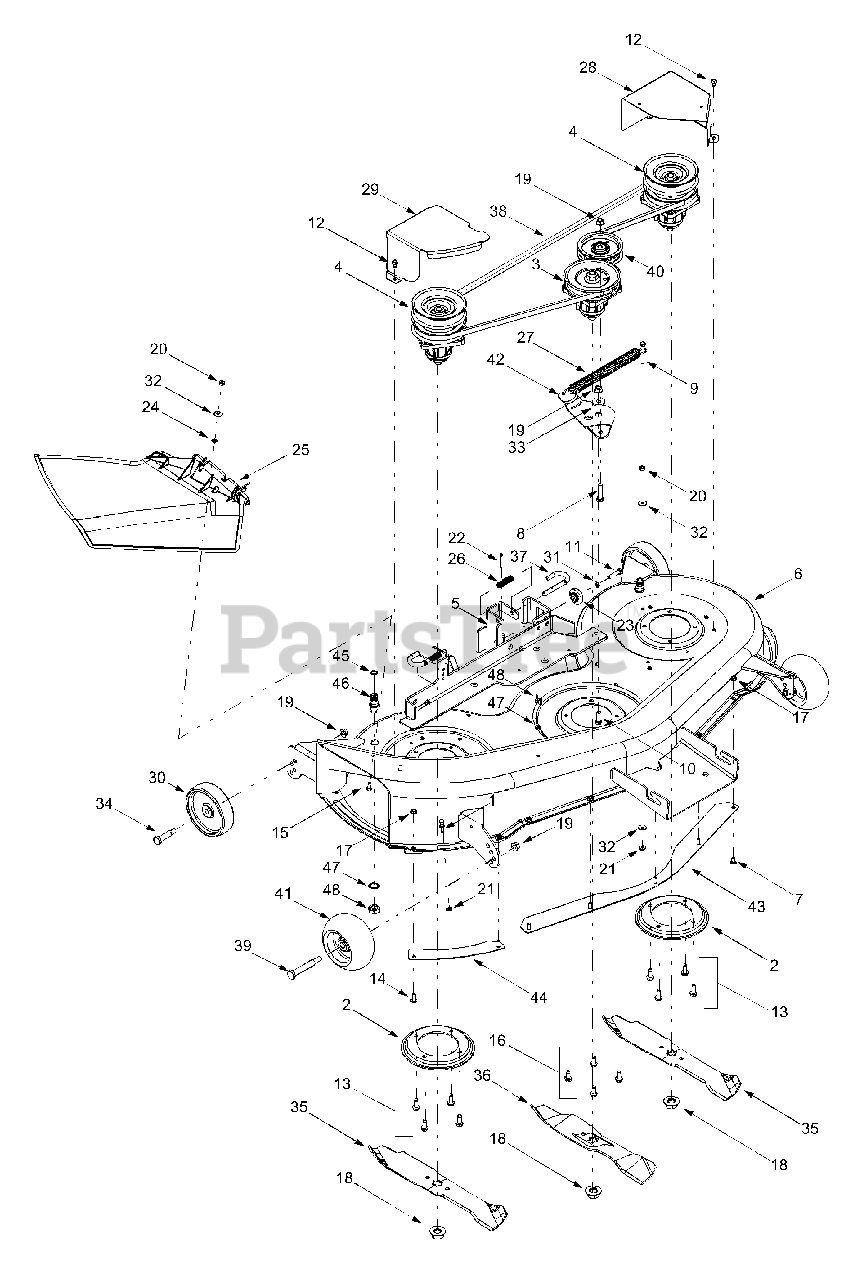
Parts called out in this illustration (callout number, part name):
1	Grass Catcher Pin, 1/4-20
4	Double Pulley Spindle Assembly
8	Hex Cap Screw, 3/8-16 x 1.5
9	Hex Cap Screw, 1/4-20 x 2.0
10	Hex Cap Screw, 3/8-16 x 1.0
11	Hex Cap Screw, 5/8-18 x 1.25
12	Self-tapping Screw,1/4-20 x .5
13	Self-tapping Screw,15/16-18 x .875
14	Hex Screw, 1/4-20 x .75
15	Hex Cap Screw, 1/4-20 x .62
16	Self-tapping Screw, 5/16-18 x .75
17	Hex Sems Nut, 1/4-20
18	Hex Flange Nut, 5/8-18
19	Flange Lock Nut, 3/8-16
20	Hex Nut, 1/4-20
21	Hex Flange Lock Nut, 1/4-20
22	Cotter Pin, 1/8 x 1.25
23	Deck Adjustment Gear
24	Push Nut. .25 x .5
25	Side Discharge Chute Assembly
26	Compression Spring, .406 x .531 x 1.75
27	Extension Spring, .91 x 7.3
31	Lock Washer, 5/16
32	Bell Washer, .265 x .75 x .062
33	Shoulder Spacer, .625 x 1.16
34	Shoulder Screw
35	Three-in-one Blade, Star Center, 16.28"
36	Three-in-one Blade, Star Center, 14.88"
37	Deck Release Pin
38	Deck Belt, Poly
39	Shoulder Screw, 1/2-2.5
40	Idler Pulley, 3.5
41	Deck Wheel, 5.0
45	O-Ring
46	Water Nozzle
47	Lock Washer, 17 x 23.8 x 1.95
48	Hex Nut, M-16 x 1.5
